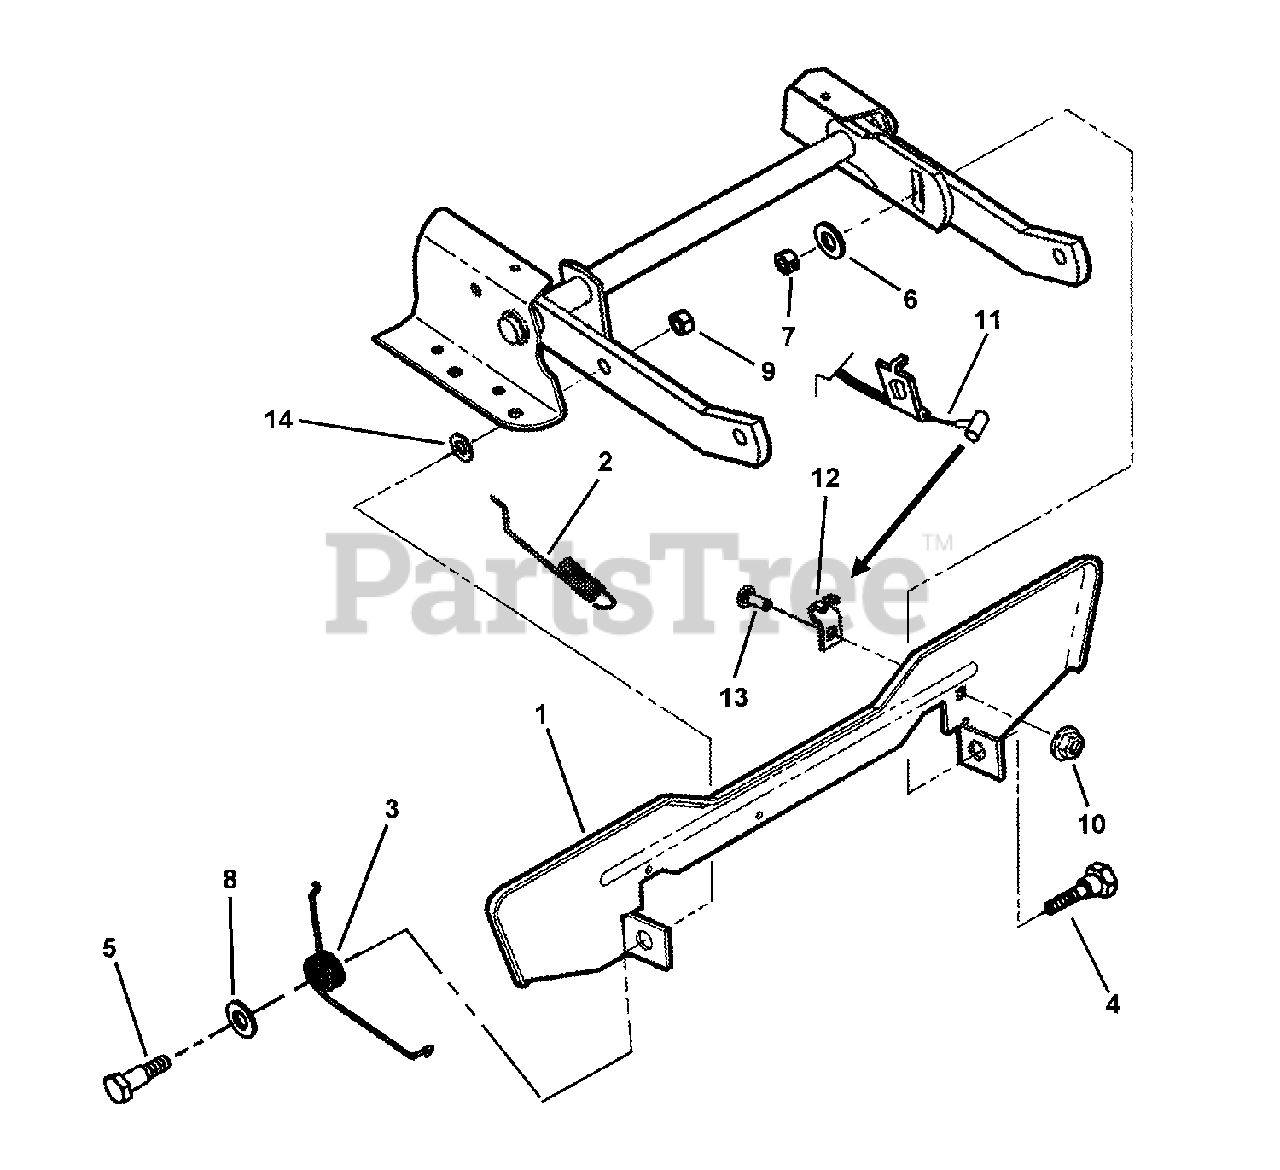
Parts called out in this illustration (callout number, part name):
1	FOOT PEDAL, Blade Stop Control
2	SPRING, Latch, .072 DIA.
3	SPRING, Pedal
4	SHOULDER BOLT, 3/8-24 w/Nylon Patch, GR 5
5	SHOULDER BOLT, 3/8-24 x 9/16"
6	WASHER, 13/32 x 1-1/4" Flat
7	NUT, 3/8-24 Hex, GR 5 or B
8	WASHER, 1/2" Flat SAE
9	NUT, 3/8-24 Hex Center Lock
10	NUT, 1/4-20 Hex Flange Lock, GR 5
11	CABLE ASSEMBLY, No Reverse in Mow
12	CLIP, Cable
13	BOLT, 1/4-20 x 3/4" Square Neck Carriage, GR 5
14	WASHER, 3/8" Flat
